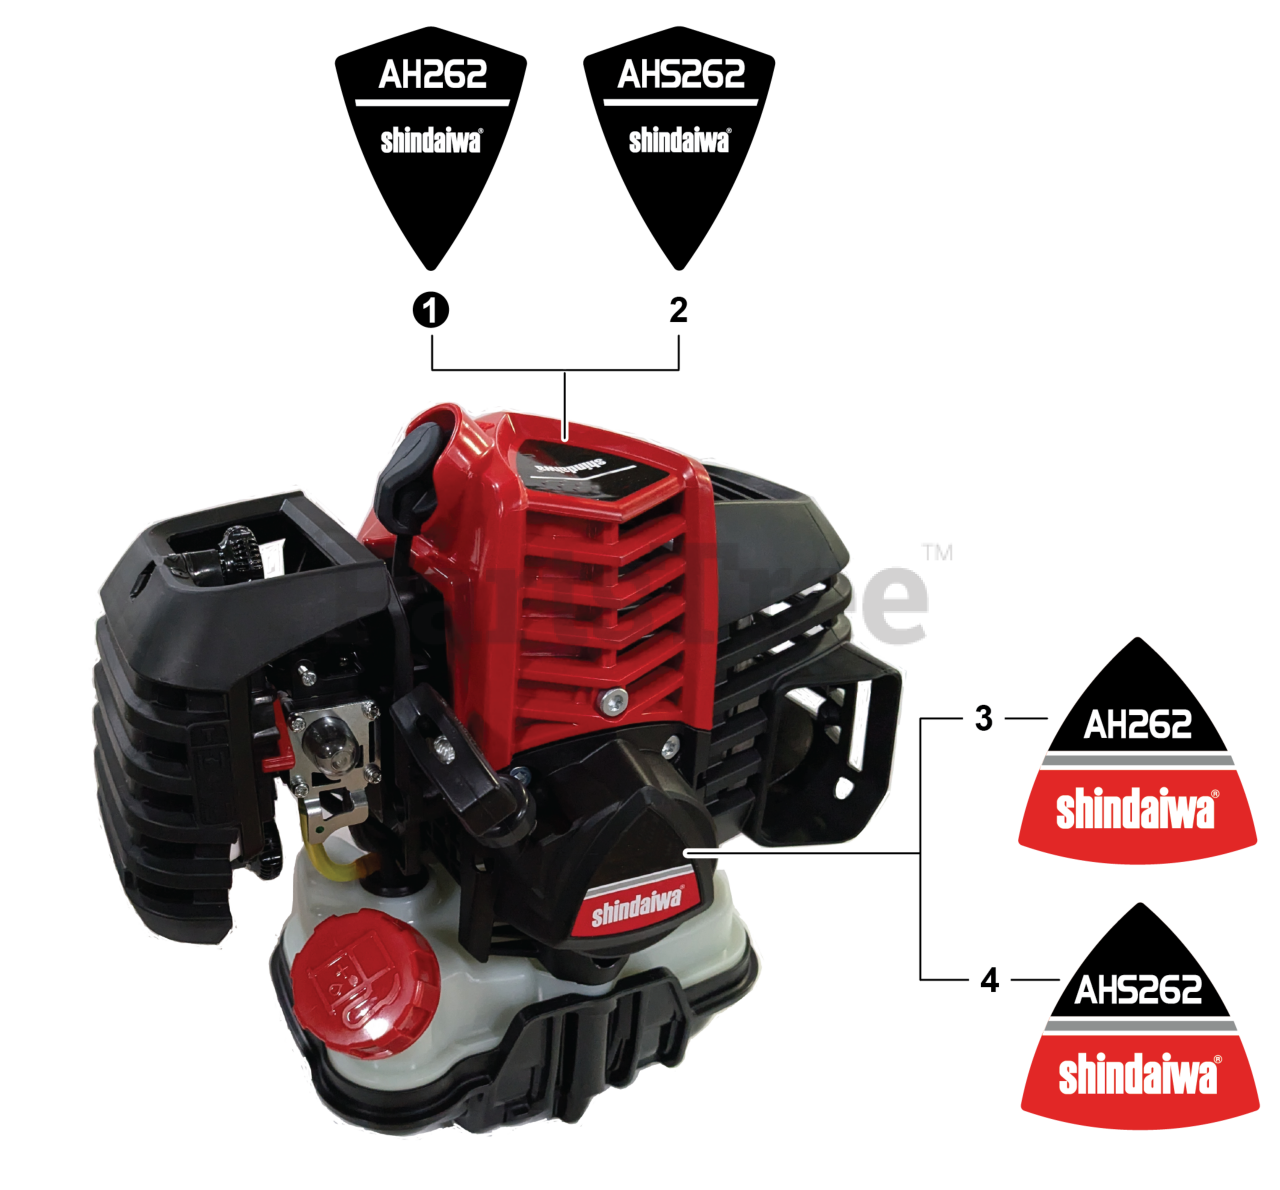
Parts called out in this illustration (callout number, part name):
1	LABEL - MODEL AH262
2	LABEL - MODEL AHS262
3	LABEL - RECOIL STARTER - AH262
4	LABEL - RECOIL STARTER - AHS262
